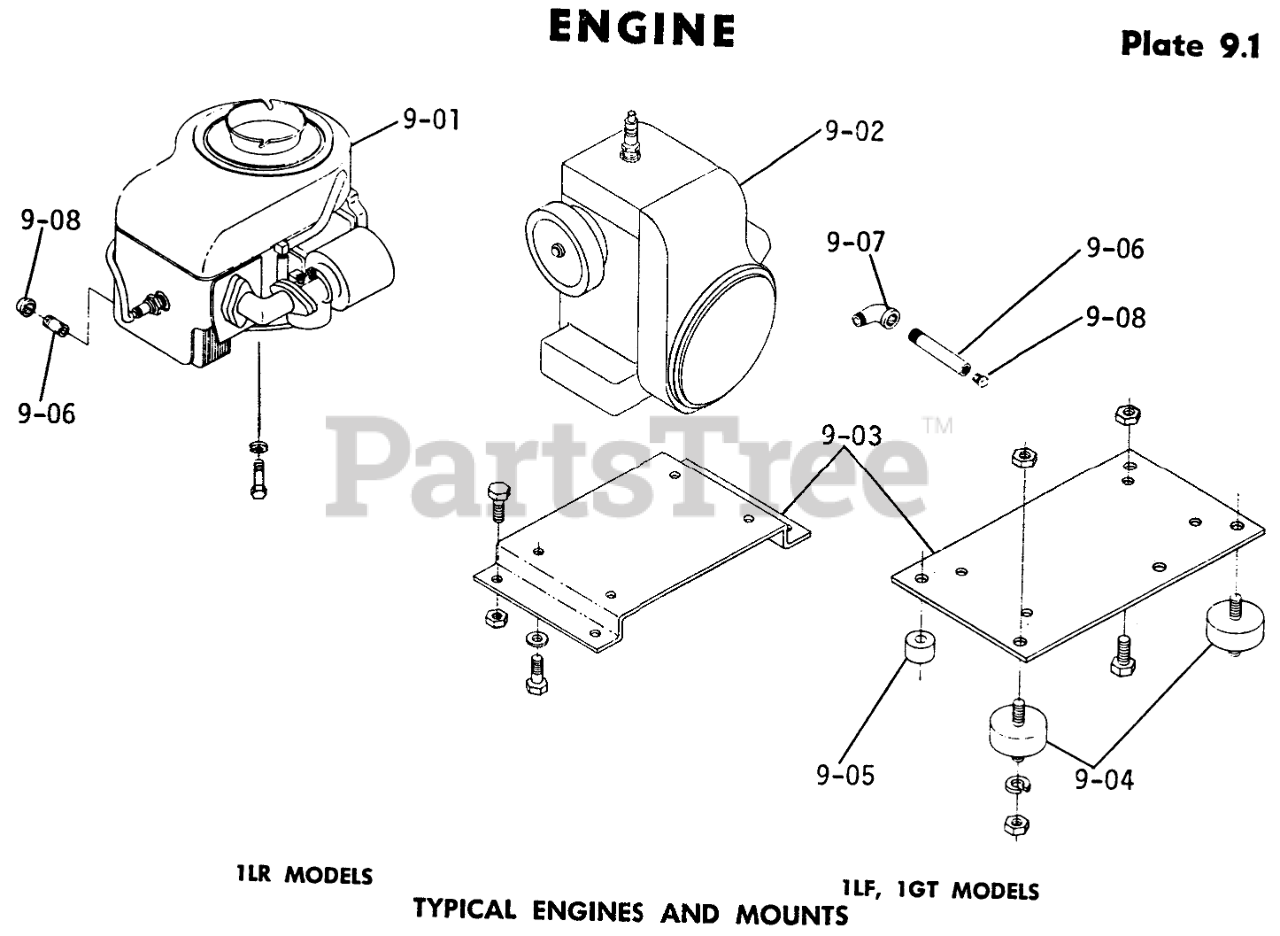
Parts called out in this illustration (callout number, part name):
9-01	Engine 7 HP
9-01	Engine 7 H.P. Electric
9-01	Hex Cap Screw
9-01	Bolt 5/16-18 x 1
9-01	Washer
9-02	Engine-8 HP-Briggs Stratton
9-02	Engine-8 HP-Lauson
9-02	Engine-10 H.P.-R10
9-02	Engine-12 H.P.-R12
9-02	Engine-14 HP-Kohler
9-02	Bolt 3/8-16 x 1
9-02	Lockwasher
9-02	Bolt, 3/8-16 x 1/2
9-02	3/8-16 E.S.
9-03	Base-Engine Mounting
9-03	Hex Cap Screw
9-03	Nut 5/16-18
9-03	Base Engine
9-03	Bolt 3/8-16 x 7/8
9-03	Lockwasher
9-03	Bolt 3/8-16 x 1
9-03	3/8-16 E.S.
9-04	Lockwasher
9-04	3/8-16 E.S.
9-05	Bolt Hex 3/8-16
9-05	3/8-16 E.S.
9-06	Nipple-A x 1 1/4 Oildrain
9-07	Elbow-3/8 x 90?
9-08	Plug-Pipe 1/4-18 Sq. Hd.
